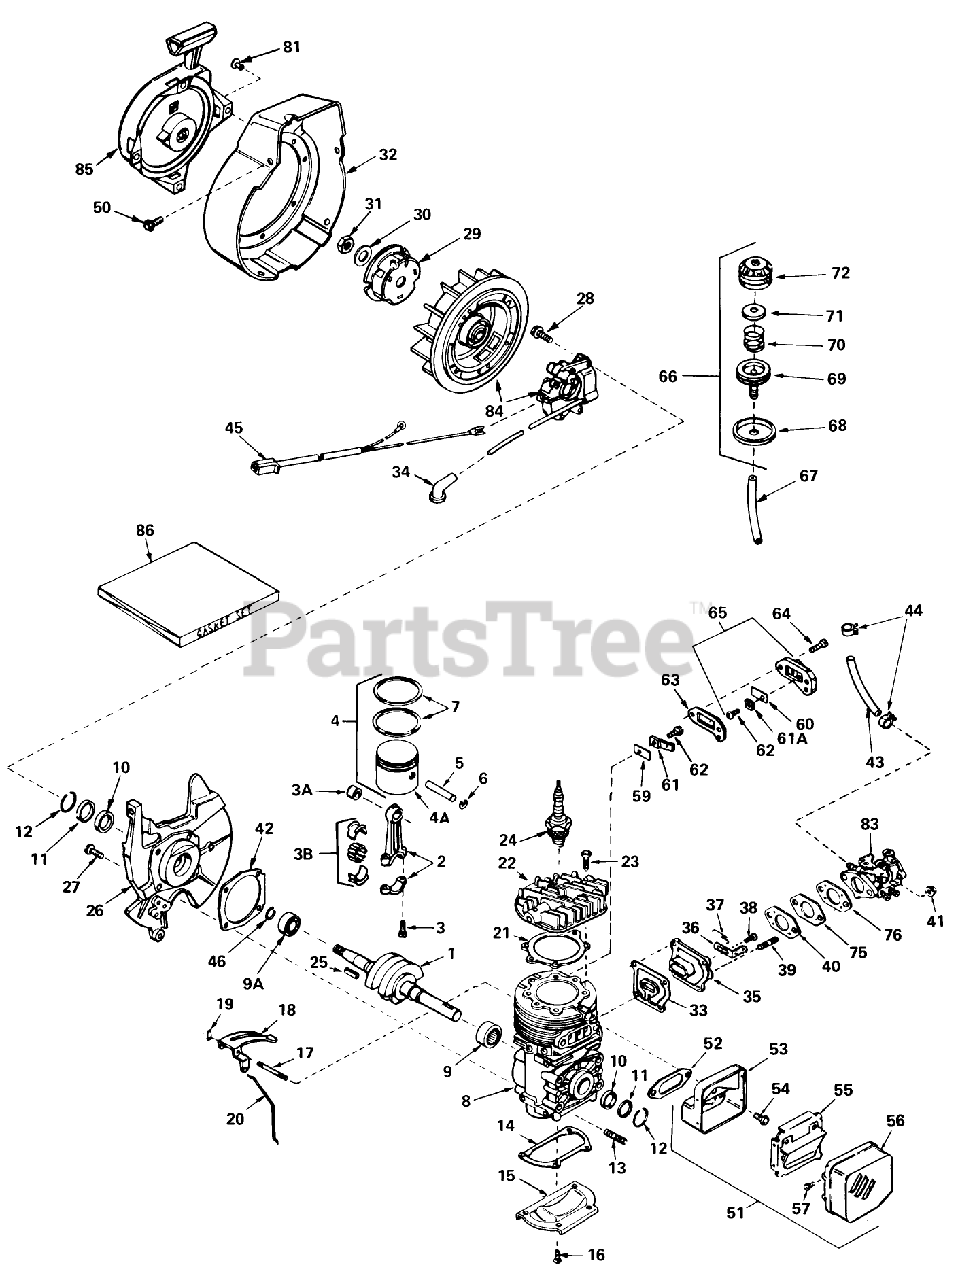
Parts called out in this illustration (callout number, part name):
1	Crankshaft
2	Rod Assembly, Connecting (Incl. #3, 3A 3B)
3	Bolt-Rod, Connecting
3A	Bearing-Cartridge
3B	Bearing Liner Set Needle
4	Piston, Pin Ring Assy. (Incl. Ref. #6 thru 9)
4A	Piston
5	Pin, Piston
6	Ring-Retaning
7	Ring Set
8	Block Assy., Cylinder (Incl. Ref. #9, 10 thru 13, 17 40)
9	Bearing-Cartridge
9A	Bearing-Ball
10	Seal, Crankshaft
11	Retainer, Crankshaft Seal
12	Spring, Crankshaft Seal Retainer
14	Gasket, Cover
15	Plate, Cover
16	Screw (T-25, 10-24 x 1/2)
17	Shaft, Air Vane
18	Vane Assy., Air
19	Clip,Air Vane
20	Link, Governor
21	Gasket, Head
22	Head-Cylinder
23	Screw (T-30, 1/4-20 x 3/4)
24	Head Adjustment Knob
25	Key-Flywheel
26	Base Assy., Housing (Incl. Nos. 29, 30 31)
27	Screw
28	Screw, Hex Washer Hd.
29	Starter Cup
30	Washer-Spring
31	Nut-Flywheel
32	Housing, Blower
33	Gasket, Port
34	Cover-Spark Plug
35	Adapter, Cover
36	Lever, Adjusting
37	Spring, Adjusting Lever
38	Screw
40	Gasket, Carburetor 1/8" thick)
41	Locknut
42	Gasket, Shroud Base
43	Line-Fuel (8.62)
44	Clamp-Line, Fuel
45	Harness, Wire
46	Ring, Retaining
50	Screw-Hex, Hd.
51	Muffler Assembly (Incl. #53-57)
52	Gasket-Muffler
53	Base-Muffler
54	Screw
55	Baffle, Muffler
56	Cover, Muffler
57	Screw
59	Reed, Compression Release
60	Reed, Compression Release
61	Plate, Reed Hold Down
61A	Plate, Reed Hold Down
62	Screw
63	Gasket, Compression Release
64	Screw
65	Cover Assy., Compression release (Incl. Nos. 60, 61A 62)
66	Primer Assy.
67	Line, Primer
68	Retainer, Primer Bulb
69	Body, Primer
70	Spring, Primer Bulb
71	Washer, Primer Bulb
72	Bulb-Primer
75	Spacer
76	Gasket, Carburetor (1/16"thick)
81	Rivet, Pop (3/16" dia.)(Can be purchased locally.)
83	Carburetor (Incl. Ref. #76) (Used on Type 1584A)
84	Magneto
85	Starter-Rewind
86	Gasket Set (Incl. items marked *)
